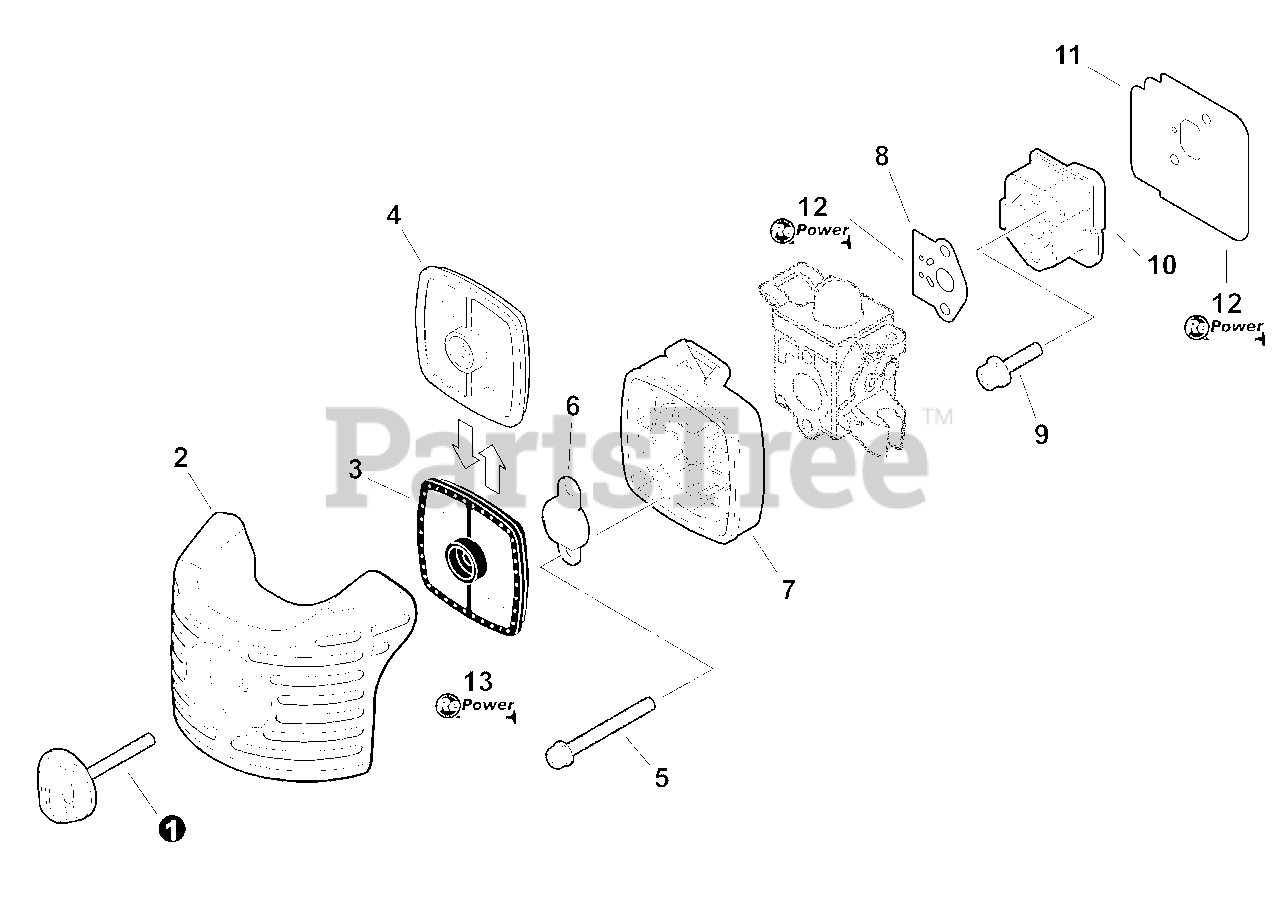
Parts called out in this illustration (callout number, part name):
1	THUMBSCREW
2	COVER, AIR FILTER
3	FILTER, AIR - DOUBLE LAYER
4	FILTER, AIR - SINGLE LAYER
5	SCREW 5×65
6	PLATE, PREVENT
7	CASE ASSY, AIR FILTER
8	GASKET, INTAKE
9	INSULATOR, INTAKE
10	BOLT 5×25
11	HEAT SHIELD, INTAKE
12	GASKET KIT
13	FILTER KIT - REPOWER
13	TUNE-UP KIT - REPOWER
